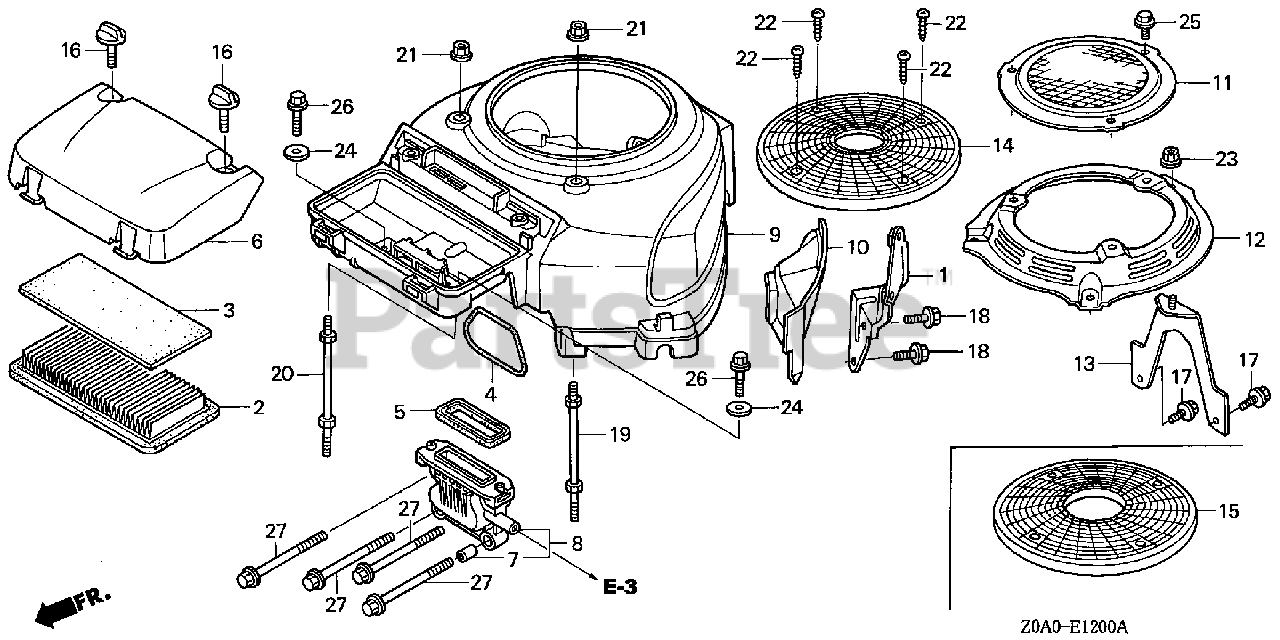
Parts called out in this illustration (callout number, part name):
1	STAY, FUEL PUMP
2	ELEMENT, AIR CLEANER
3	FILTER (OUTER)
4	GASKET, AIR CLEANER
5	SEAL, AIR CLEANER HOUSING
6	COVER, AIR CLEANER
7	COLLAR A, AIR CLEANER
8	ELBOW, AIR CLEANER
9	COVER, FAN *NH1* (BLACK)
10	PLATE, SIDE
14	GRID, SCREEN *NH1* (BLACK)
16	BOLT, AIR CLEANER (6MM)
17	BOLT, FLANGE (6X14) (CT200)
18	BOLT, FLANGE (6X14)
19	BOLT, L. STUD (IGNITION COIL)
20	BOLT, R. STUD (IGNITION COIL)
21	NUT, FLANGE (6MM)
22	SCREW, TAPPING (4X30) (P0)
24	WASHER, PLAIN (6MM)
26	BOLT, FLANGE (6X12)
27	BOLT, FLANGE (6X100)
